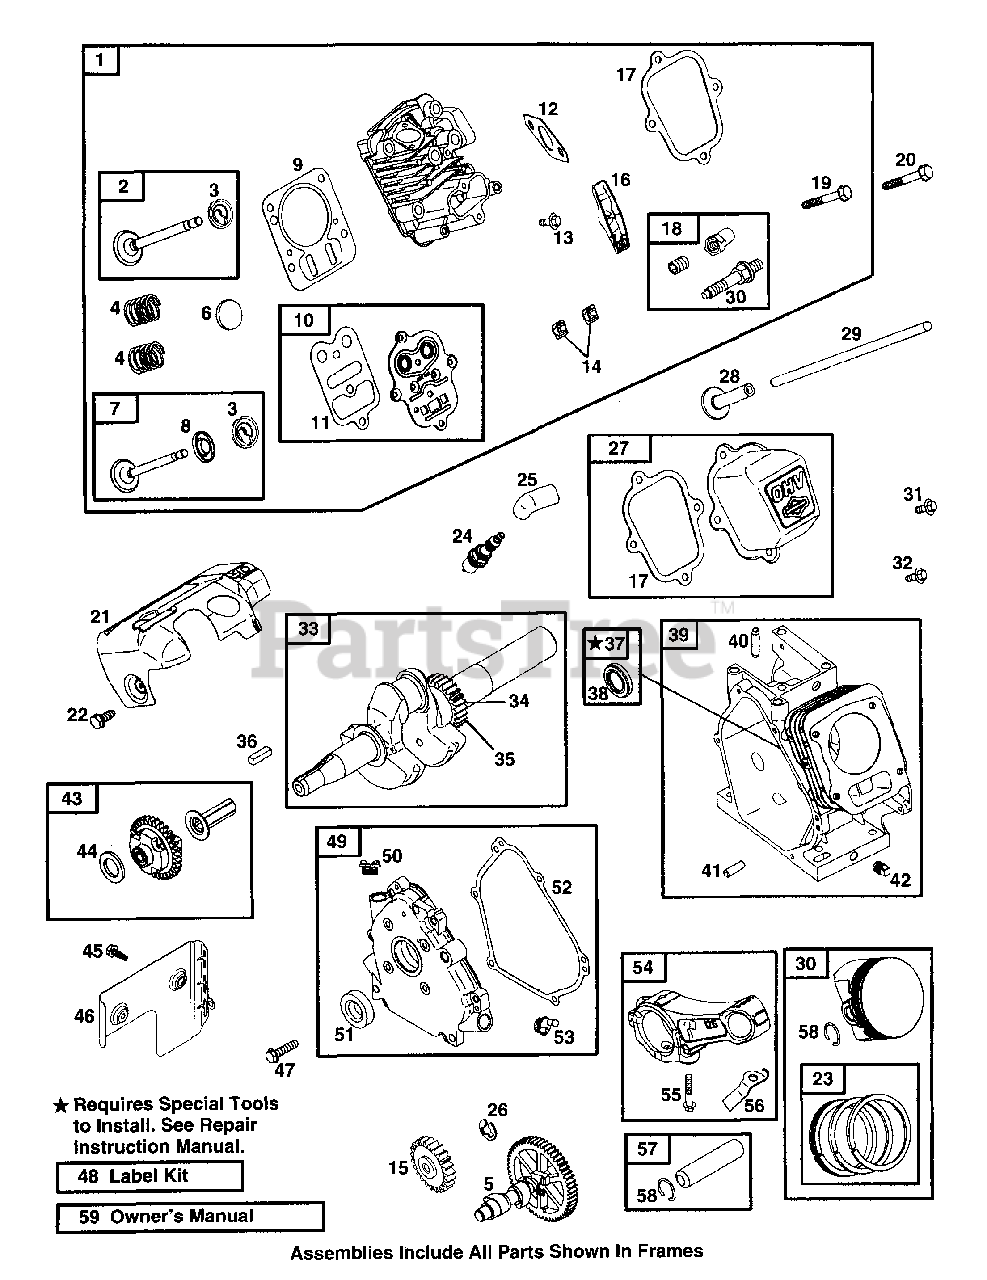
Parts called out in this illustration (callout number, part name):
1	Cylinder Head
2	Exhaust Valve
3	Valve Retainer
4	Valve Spring (Intake)
7	Intake Valve
8	Valve Seal
9	Cylinder Head Gasket
10	Cylinder Head Plate
11	Cylinder Head Plate Gasket
12	Intake Gasket
13	Screw (Cylinder Head Plate)
14	Guide-Push Rod
15	Gear-Idler
16	Rocker Arm
17	Rocker Cover Gasket
18	Rocker Arm Ball
19	Screw (Rocker Arm)
20	Screw (Cylinder Head)
21	Shield-Cylinder
22	Screw (Cylinder Shield)
23	Ring Set (Standard)
25	Boot-Spark Plug
26	Ring-Retaining
27	Rocker Cover
28	Valve Tappet
30	Piston Assembly (Standard)
31	Screw (Rocker Cover 3/8" Long)
32	Screw (Rocker Cover 7/16" Long)
33	Crankshaft
34	Timing Key
35	Gear-Timing
36	Flywheel Key
37	Bushing/Seal Kit
38	Oil Seal
39	Cylinder Assembly
40	Bushing-Governor Crank
41	Locating Pin
42	Oil Drain Plug
43	Governor Gear
44	Washer (Governor Gear)
45	Screw (Panel)
46	Panel
47	Screw (Crankcase Cover)
49	Crankcase Cover
52	Crankcase Gasket
53	Oil Fill Cap
54	Connecting Rod
55	Screw (Connecting Rod)
56	Connecting Rod Dipper
57	Piston Pin
58	Piston Pin Lock
59	Owner's Manual
